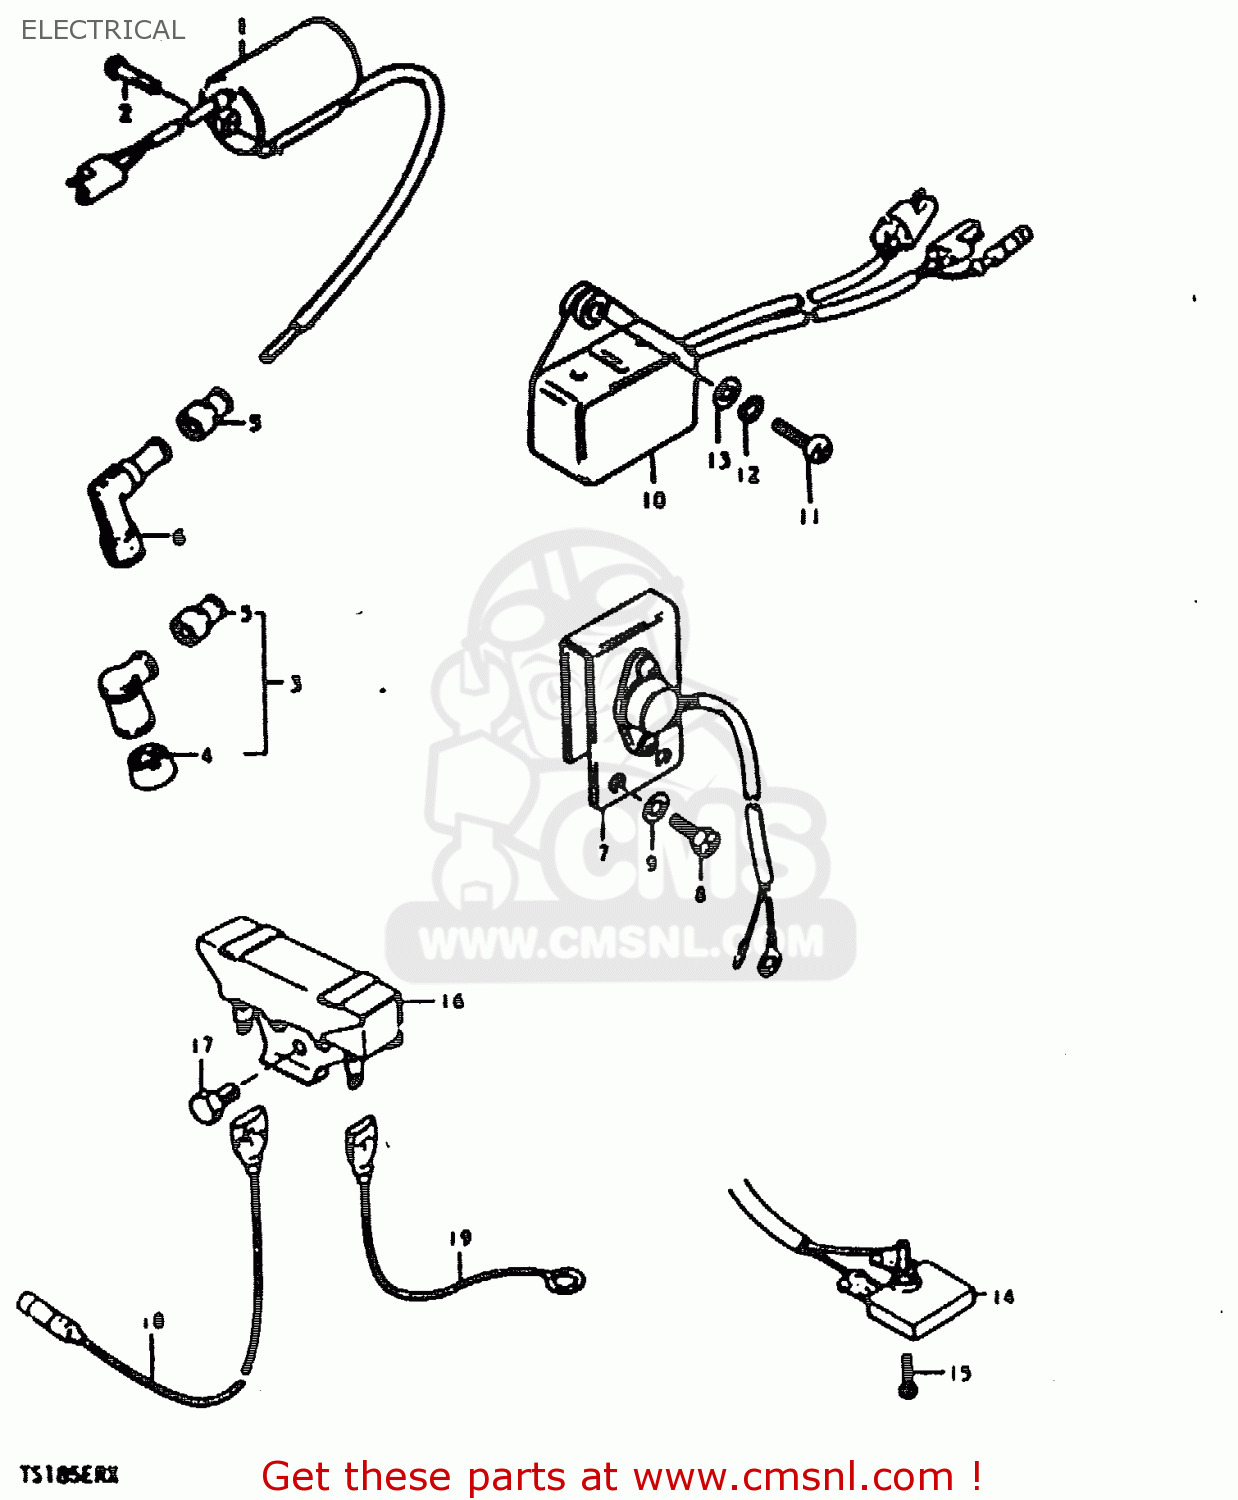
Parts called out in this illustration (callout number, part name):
1	COIL ASSEMBLY,IGNITION
2	SCREW 5X20
5	SEAL,SPARK PLU
6	CAP,SPARK PLUG
7	REGULATOR ASSEMBLY
8	SCREW(5X12)
9	WASHER
10	CDI UNIT
11	SCREW
12	LOCK WASHER
13	WASHER
14	RECTIFIER ASSEMBLY
15	SCREW
